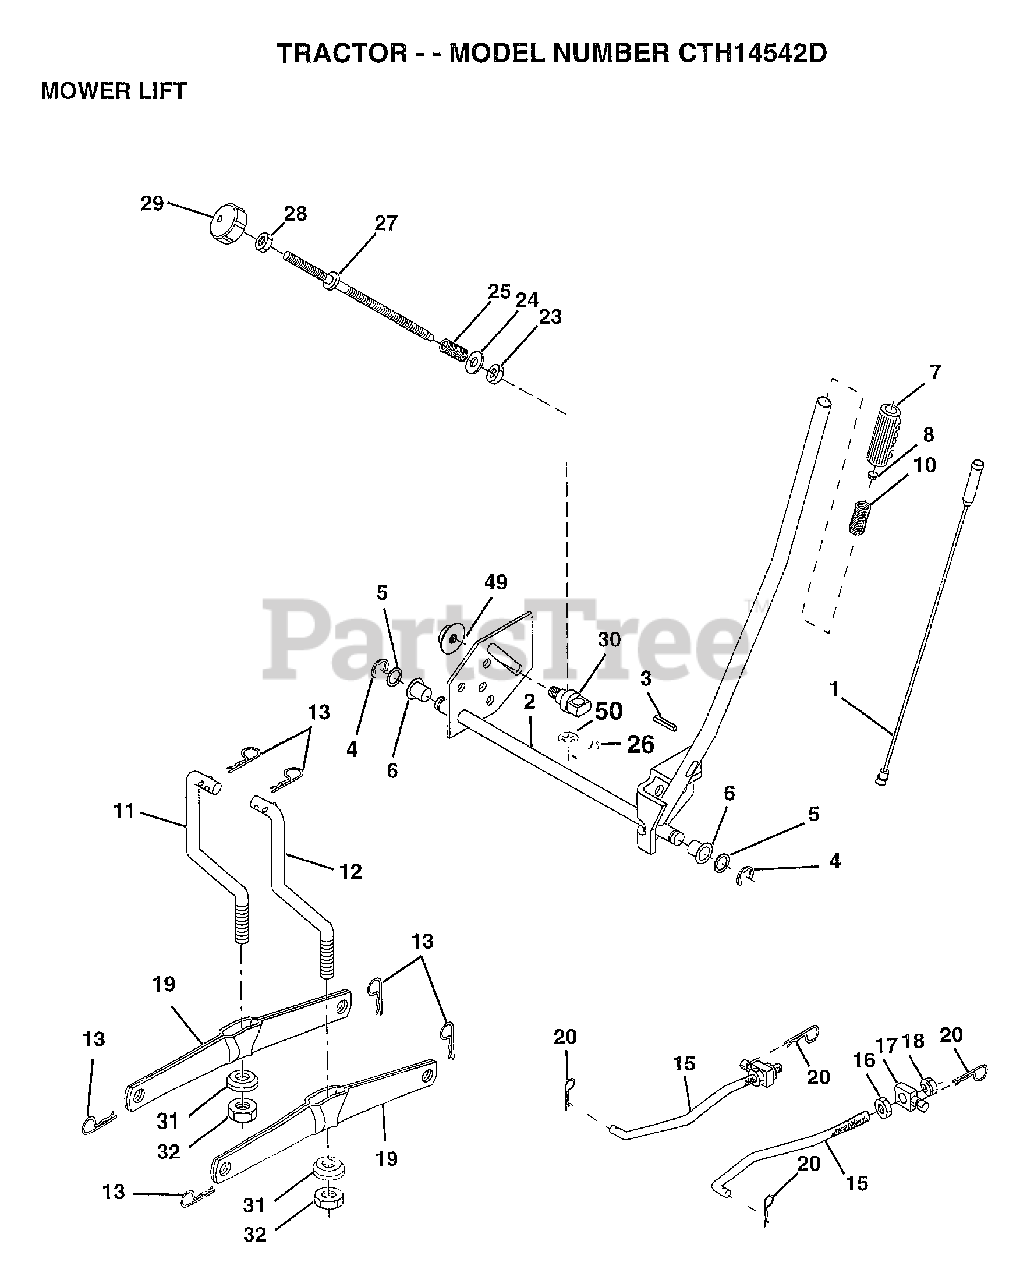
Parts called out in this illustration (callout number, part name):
1	WIRE.ASM.INNER
2	SHAFT.ASM.LIFT.RH
3	PIN GROOVE
5	WASHER
6	NYLON BEARING
7	GRIP
8	BUTON PLUNGER
15	LINK.FRONT
16	NUT
17	TRUNION
18	NUT.LK.W/WSH.1/2.
19	ARM SUSP REAR
20	RETAINER.SPRING
23	NUT T
24	WASHER
25	SPRING.COMP.INF.H
27	ROD.ADJ.LIFT
28	NUT
29	KNOB INF 3/8-16
30	TRUNNION
31	BEARING PVT LH
32	NUT.CROWNLOCK.3/8
49	NUT.HXFLG.LOCK.
50	NUT PUSH M
